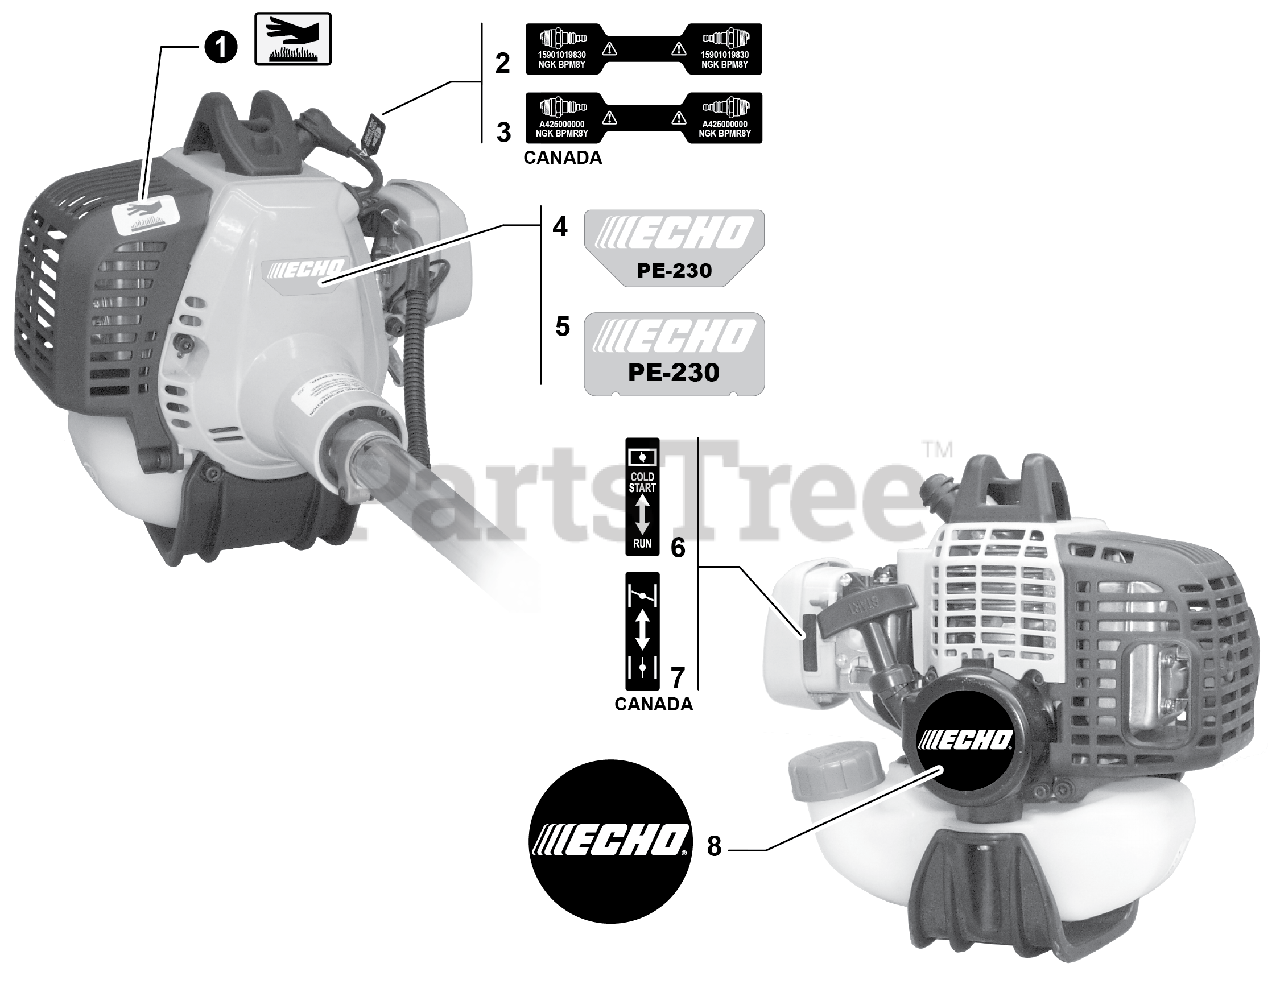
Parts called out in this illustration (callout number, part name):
1	LABEL, CAUTION - HOT
2	LABEL, SPARK PLUG - BPM8Y
3	LABEL, SPARK PLUG - BPMR8Y
4	LABEL, MODEL - PE-230
5	LABEL, MODEL - PE-230
6	LABEL, CHOKE
7	LABEL, CHOKE
8	LABEL, RECOIL STARTER
